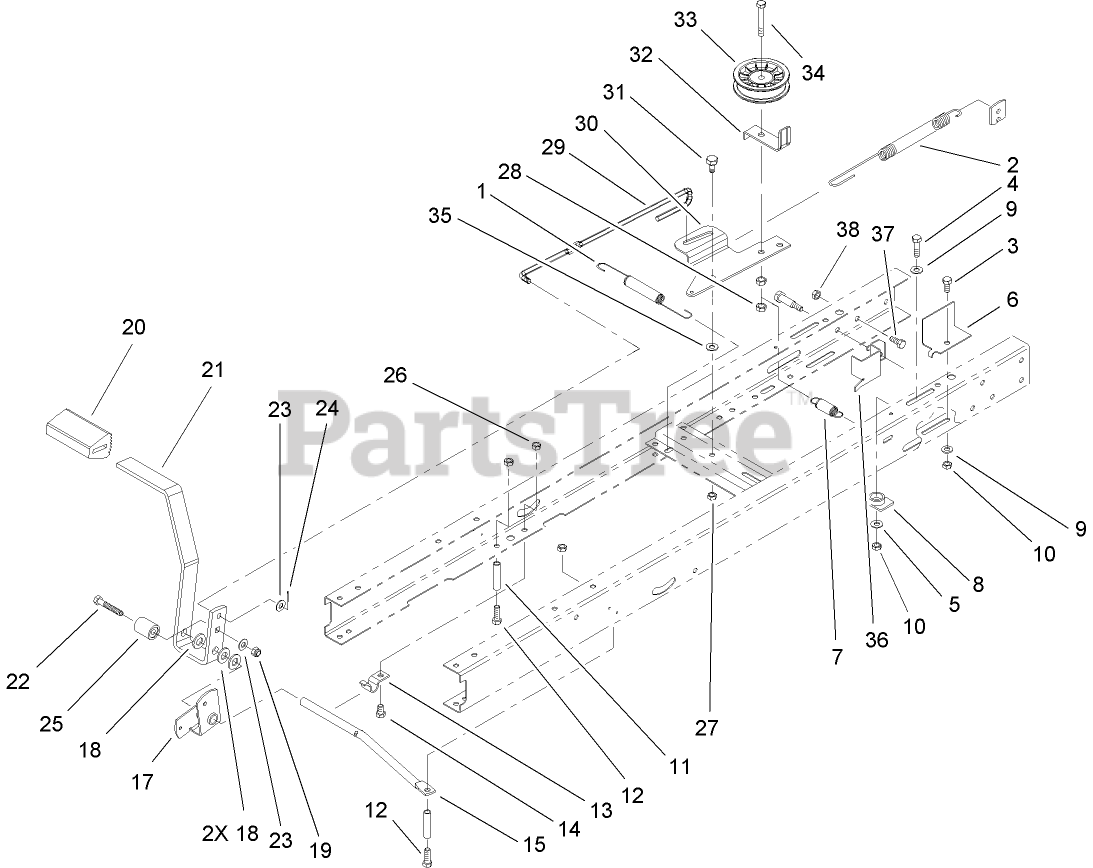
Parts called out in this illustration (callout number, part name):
1	SPRING-EXTENSION
2	SPRING-BRAKE
3	SCREW-HH
4	SCREW-HH
5	WASHER-PIVOT
6	BRACKET-BELT, GUIDE
7	SPRING-EXTENSION
8	GUIDE-CABLE
9	WASHER-PLAIN
10	NUT-LOCK, NI
11	TUBING-SPACER
12	SCREW-HH
13	CLAMP-PIVOT, SHIFT
14	SCREW-HH
15	ROD-PIVOT, PEDAL
17	BELLCRANK
18	WASHER-FLAT
19	NUT-LOCK, NI
20	PAD-PEDAL
21	PEDAL-CLUTCH/BRAKE, HYDRO
22	SCREW-HH
23	WASHER-PLAIN
24	PIN-COTTER
25	SPACER
26	NUT-LOCK, NI
27	NUT-LOCK, NI
29	ROD-CLUTCH/BRAKE
30	ARM-IDLER
31	BOLT-SHOULDER
32	GUIDE-IDLER, BELT
33	PULLEY-IDLER
34	SCREW-HH
35	WASHER-PIVOT
36	BRACKET-BELT, GUIDE
37	SCREW-HH
38	NUT-LOCK, NI
